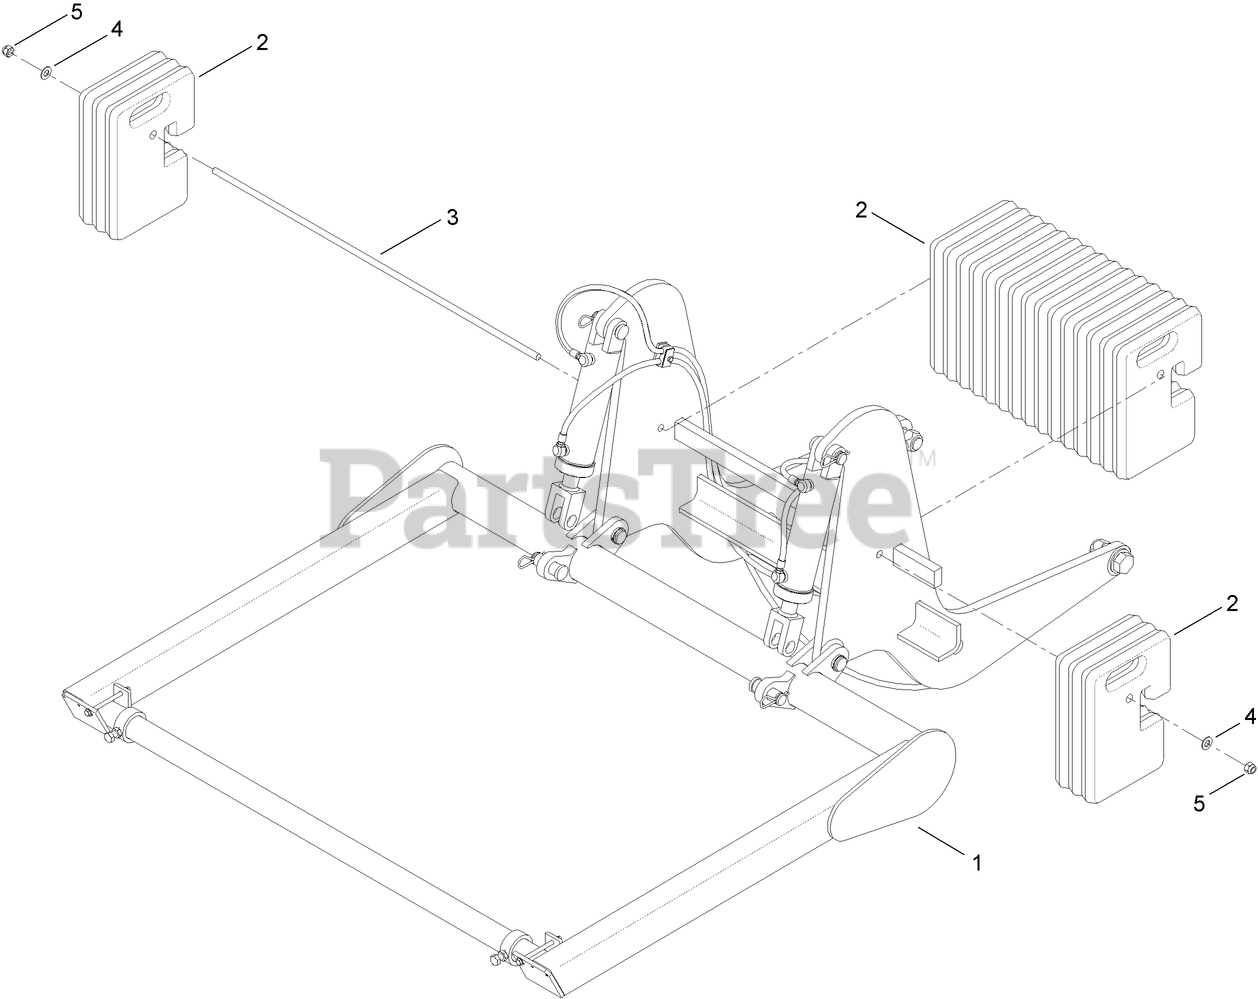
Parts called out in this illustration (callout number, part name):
1	REEL CARRIER ASM
2	COUNTERWEIGHT-60lb
3	ROD-WEIGHT
4	WASHER-FLAT
5	NUT-LOCK, HEX
